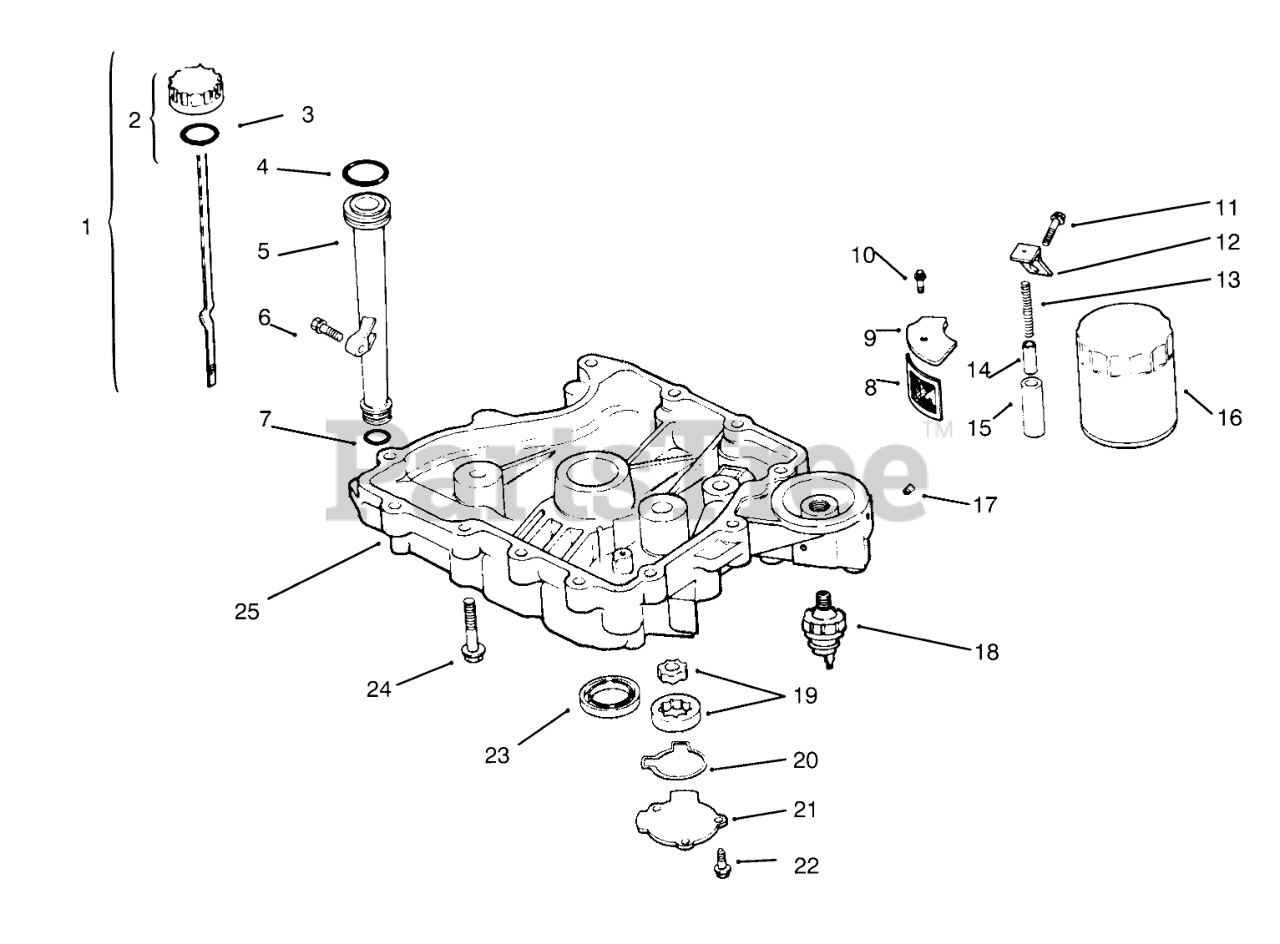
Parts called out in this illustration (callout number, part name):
1	Dipstick INCL 2-3 (Only On: 72042,72043,72062,72063)
2	Kit-Oil Cap INCL 3 (Only On: 72042,72043,72062,72063)
3	O Ring-Fill Cap (Only On: 72042,72043,72062,72063)
4	O Ring-Upper Fill Tube (Only On: 72042,72043,72062,72063)
5	Tube-Oil Fill (Only On: 72042,72043,72062,72063)
6	Screw M5X0.8X20 (Only On: 72042,72043,72062,72063)
7	O Ring-Lower Fill Tube (Only On: 72042,72043,72062,72063)
8	Screen-Oil Pickup (Only On: 72042,72043,72062,72063)
9	Cover-Oil Pickup Screen (Only On: 72042,72043,72062,72063)
10	Screw M5X0.8X16 (Only On: 72042,72043,72062,72063)
11	Screw M10X1.5X25 (Only On: 72042,72043,72062,72063)
12	Bracket-Oil Pump Relief (Only On: 72042,72043,72062,72063)
13	Spring-Oil Relief Valve (Only On: 72042,72043,72062,72063)
14	Piston-Oil Relief Valve (Only On: 72042,72043,72062,72063)
15	Body-Oil Relief Valve (Only On: 72042,72043,72062,72063)
16	Filter-Oil (Only On: 72042,72043,72062,72063)
17	Plug-SH 3/8 NPTF (Only On: 72042,72043,72062,72063)
18	Switch-Oil Pressure (Only On: 72042,72043,72062,72063)
19	Pump-Oil (Only On: 72042,72043,72062,72063)
20	O Ring-Oil Pump Cover (Only On: 72042,72043,72062,72063)
21	Cover-Oil Pump (Only On: 72042,72043,72062,72063)
22	Screw M5X0.8X16 (Only On: 72042,72043,72062,72063)
23	Seal-Crankshaft (Only On: 72042,72043,72062,72063)
24	Screw M8X1.25X45 (Only On: 72042,72043,72062,72063)
25	Pan-Oil (Only On: 72042,72043,72062,72063)
